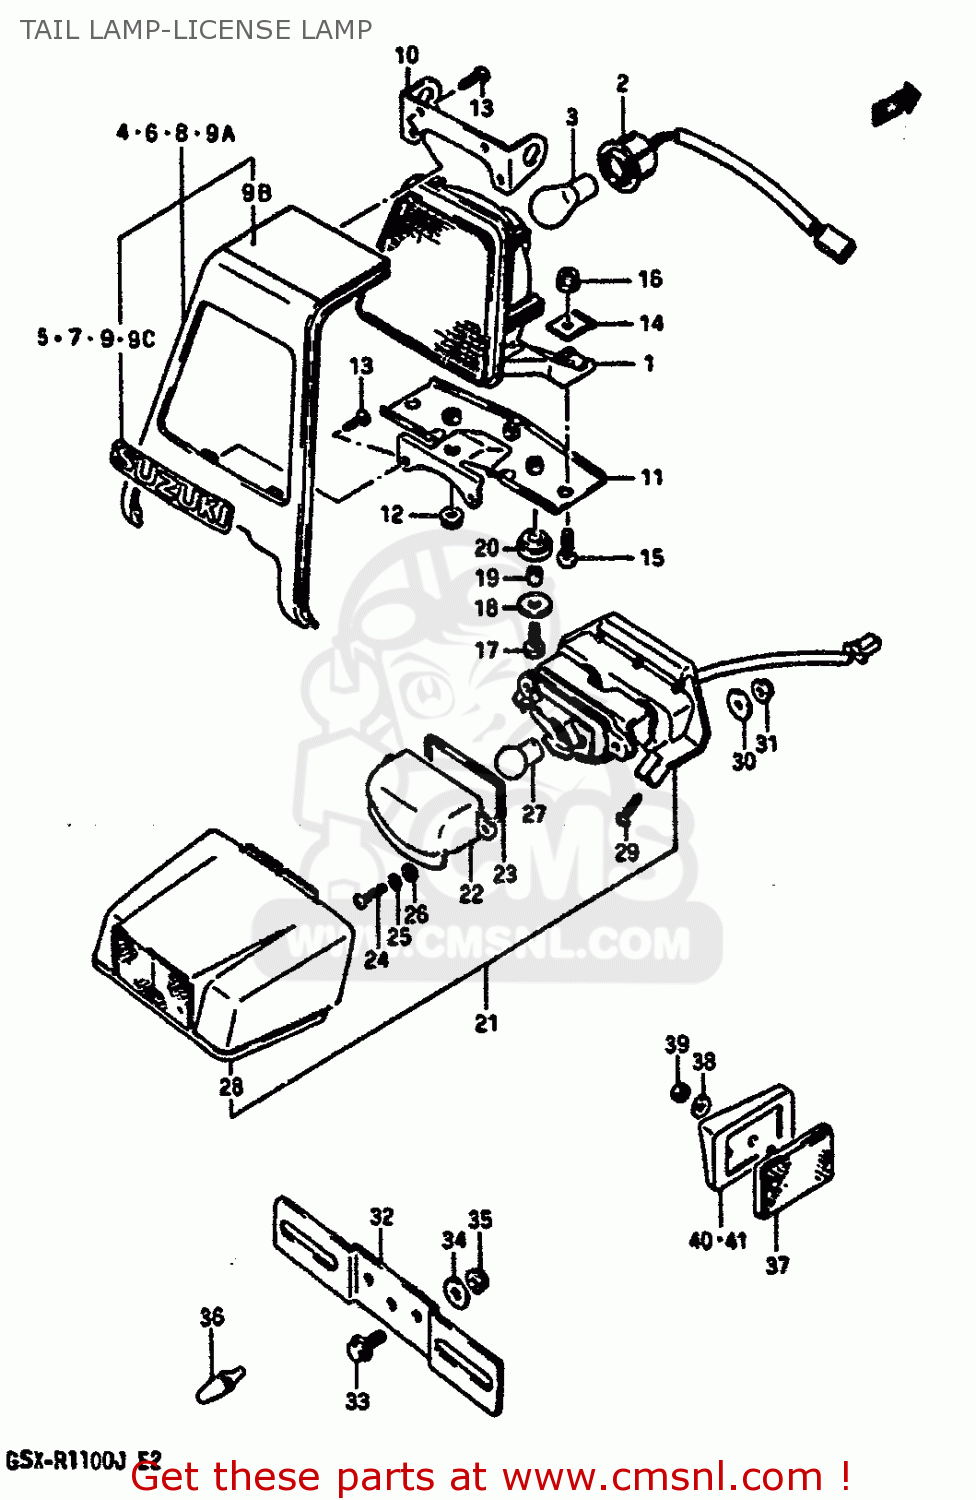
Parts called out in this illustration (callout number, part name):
1	UNIT,REAR COMBINATION LAMP
2	SOCKET & CORD ASSEMBLY
3	BULB(12V21/5W)
4	COVER,TAIL LAMP
5	EMBLEM
6	COVER,TAIL LAMP
7	EMBLEM
8	COVER,TAIL LAMP
9	EMBLEM(WHITE)
9A	COVER,TAIL LAMP
9B	TAPE,REAR COMBINATION LAMP
9C	EMBLEM
10	PLATE
11	BRACKET
12	NUT
13	SCREW
14	PLATE,TAIL LAMP
15	SCREW
16	NUT
17	BOLT,M6X1X20
18	WASHER
19	SPACER (6.1X9X7.5)
20	CUSHION
21	LAMP ASSY,LICENSE
22	LENS,LICENSE LAMP
23	GASKET,LICESE LAMP (NAS)
24	SCREW
25	WASHER,LOCK 4M
26	WASHER 4MM
27	BULB
28	COVER,LICENSE LAMP
29	SCREW
30	WASHER (5.5X20X1.2)
31	NUT
32	PLATE,RR LICENSE
33	BOLT
34	WASHER
35	NUT
36	CUSHION
37	REFLEX REFLECTOR,REAR SIDE
38	WASHER(5.2X16X1)
39	NUT
40	SPACER,REAR SIDE,REAR,RIGHT
41	SPACER,REAR SIDE,REAR,LEFT
